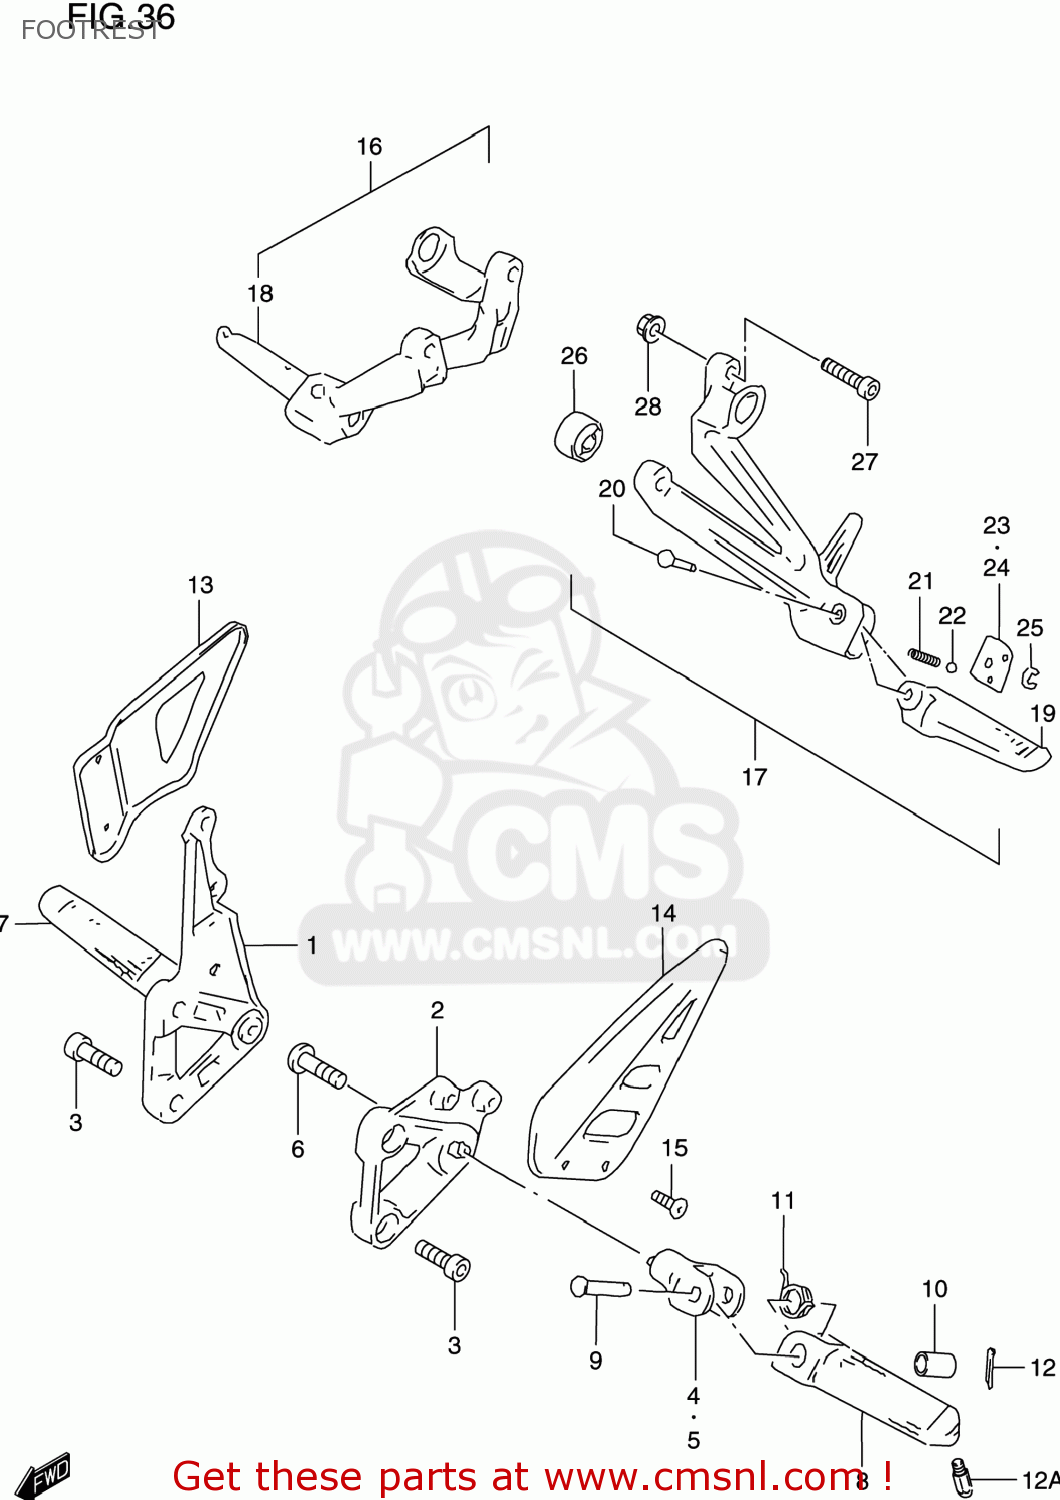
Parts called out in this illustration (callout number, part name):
1	BRACKET,FR FOOTREST,R
2	BRACKET,FR FOOTREST,L
3	BOLT
4	HOLDER,FOOTREST,R
5	HOLDER,FOOTREST,L
6	BOLT(10X28)
7	BAR,FOOTREST,R
8	BAR,FOOTREST,L
9	PIN
10	SPACER(8.1X12X22)
11	SPRING
12	PIN 20X15
12A	BOLT,BANK SENSOR
13	GUARD,FR FOOTREST,R
14	GUARD,FR FOOTREST,L
15	SCREW(5X10)
16	FOOTREST ASSY,PILLION,R
17	FOOTREST ASSY,PILLION,L
18	BAR,PILLION FOOTREST,RIGHT
19	BAR,PILLION FOOTREST,LEFT
20	PIN
21	SPRING
22	BALL
23	PLATE,PILLION FOOT,R
24	PLATE,PILLION,LEFT
25	E-RING
26	BUSH
27	BOLT
28	NUT
